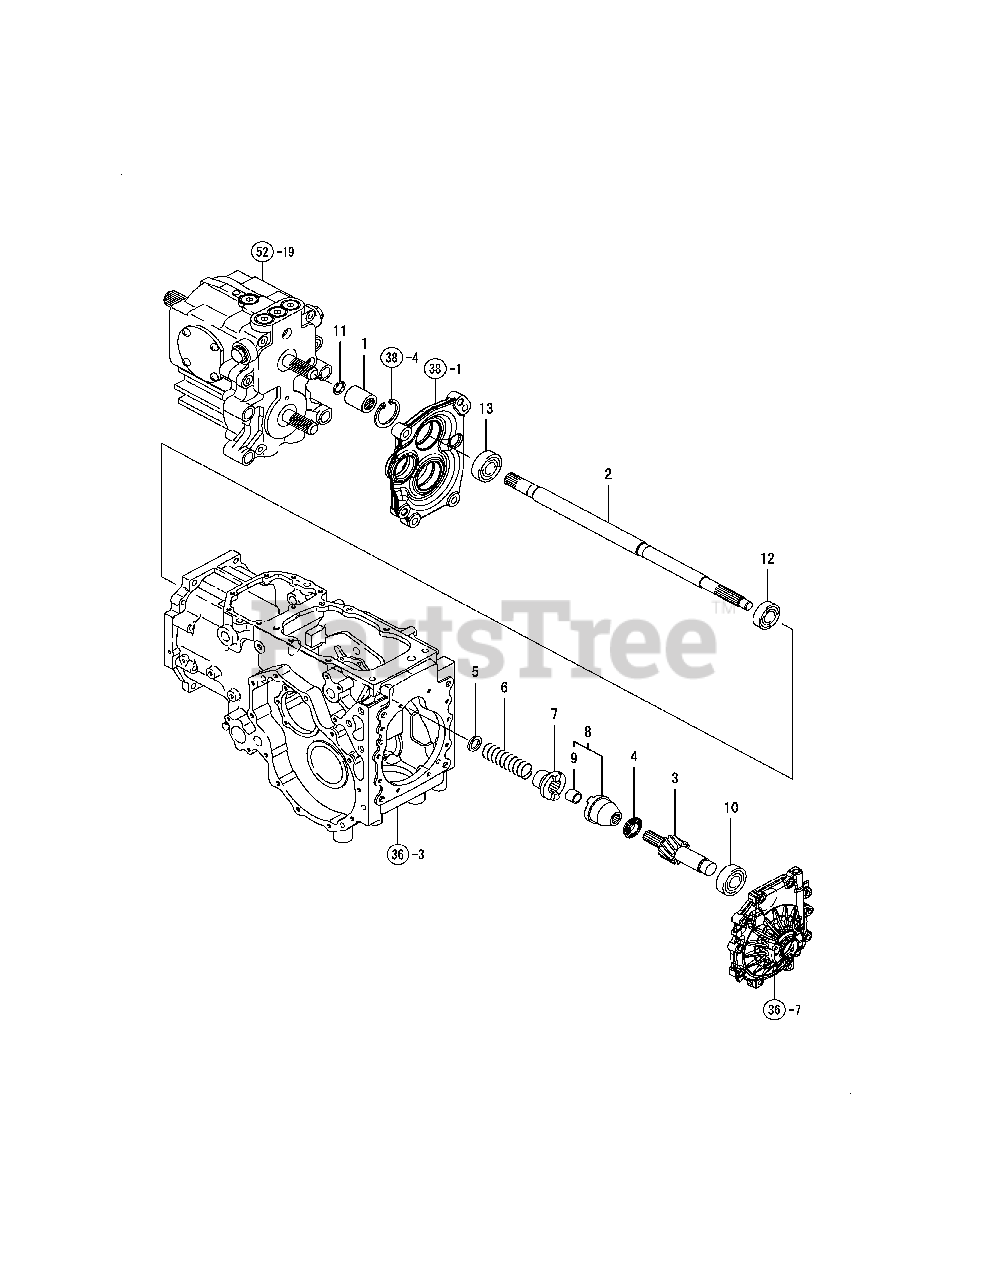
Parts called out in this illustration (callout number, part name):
2	CONNECTING SHAFT
3	SHAFT, PTO DRIVE
4	BEARING HR6303NR
5	WASHER, 17X25X3
7	CLUTCH (A), 1-WAY
10	BEARING TMB204
12	BALL BEARING #6004
13	BALL BEARING #6204
